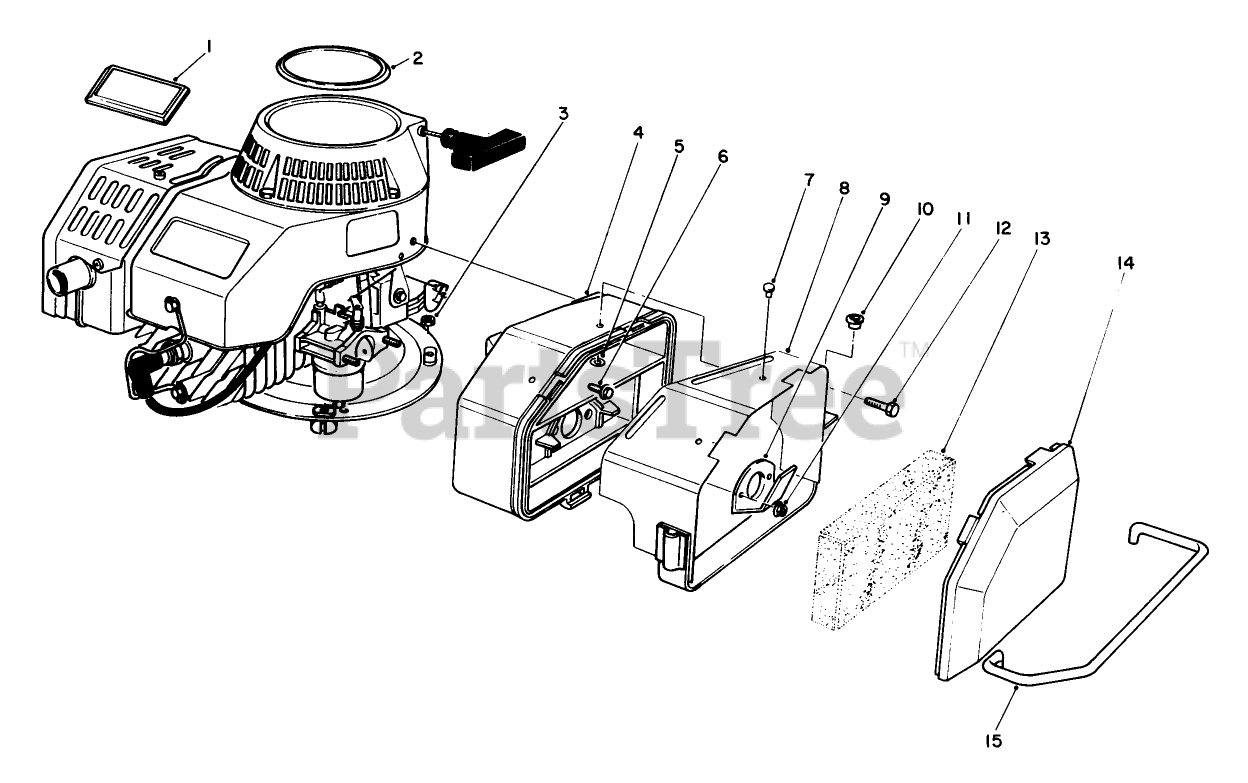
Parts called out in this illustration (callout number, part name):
3	NUT-JAM
4	AIR CLEANER ASM
5	WASHER-FLAT
7	NUT-HEX
9	SPIT BACK DEFLECTOR
12	SCREW-HHF
13	FILTER
15	AIR CLEANER GUARD*
